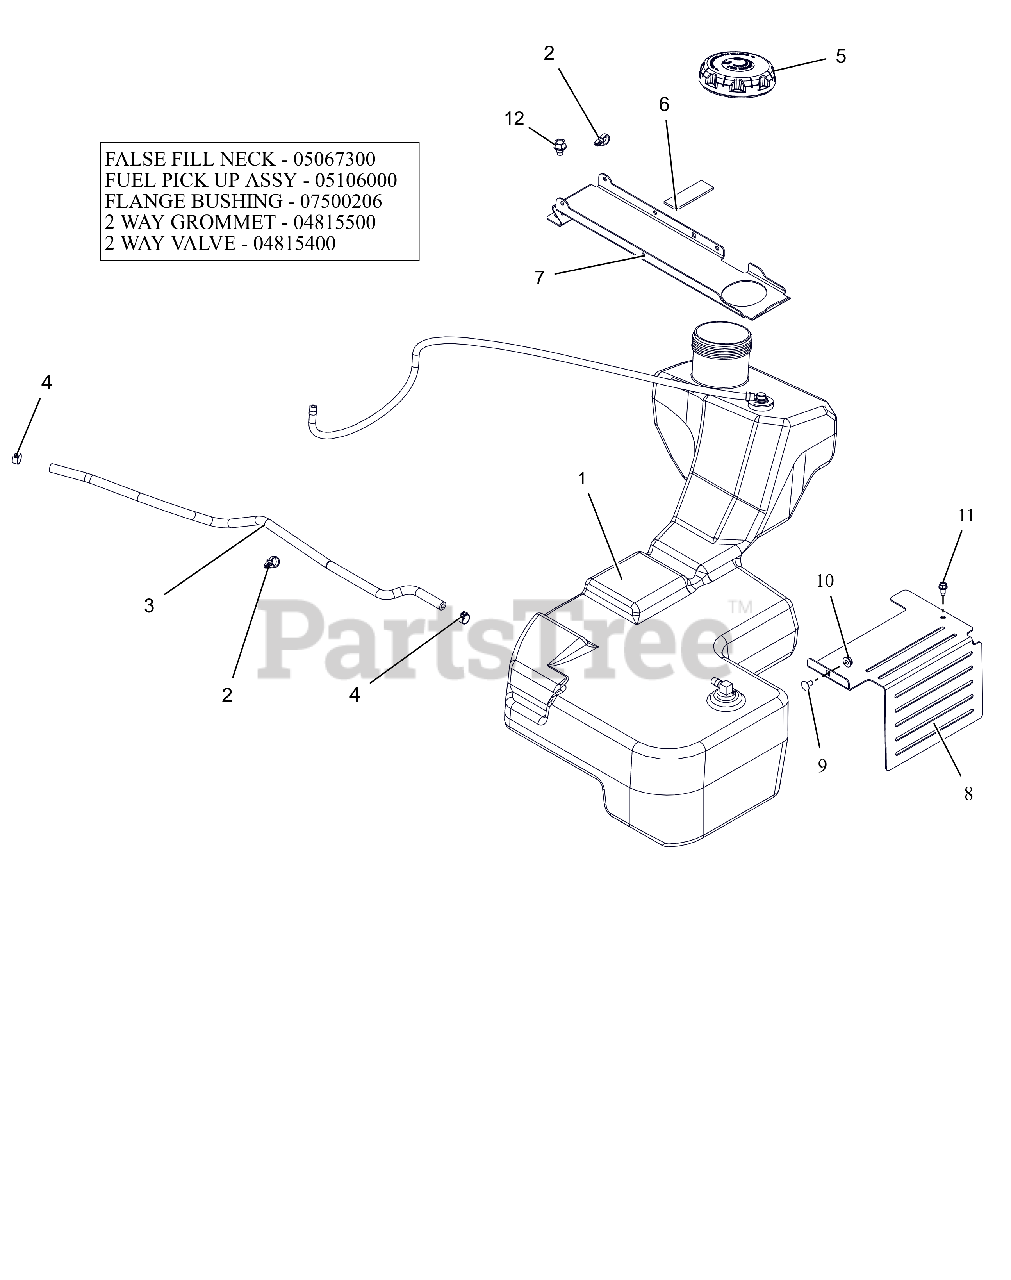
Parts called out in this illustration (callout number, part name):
1	ASM, HD FUEL TANK
1	INSERT, FUEL NECK FALSE FILL
1	ASM, HD FUEL PICK-UP
1	BSHG-FLG .375X1.062X.625 NITR
1	GROMMET, 2-WAY
1	VALVE, 2-WAY
2	ROUTING CLIP (1/2" ID)
3	HOSE, .25 LOW-PERM BULK GAS
4	CLAMP, FUEL LINE
5	CAP, FUEL VENTIN AUTOLOCK
6	PAD,RBR 1.0"X3.0" W/ADHESIVE
7	BRKT, FUEL TANK HOLD DOWN
8	GUARD, TRANSAXLE FAN LH (BLACK)
9	BLT-RDHDSQSHNK.25-20X.50 YWZC
10	NUT-LK-CTR-FLG .25-20 ZC120
11	SCR-TAP .25-20X.50 HWH ZCC
12	@SCR-TAP .38-16X.50 HWH TR YWZ
